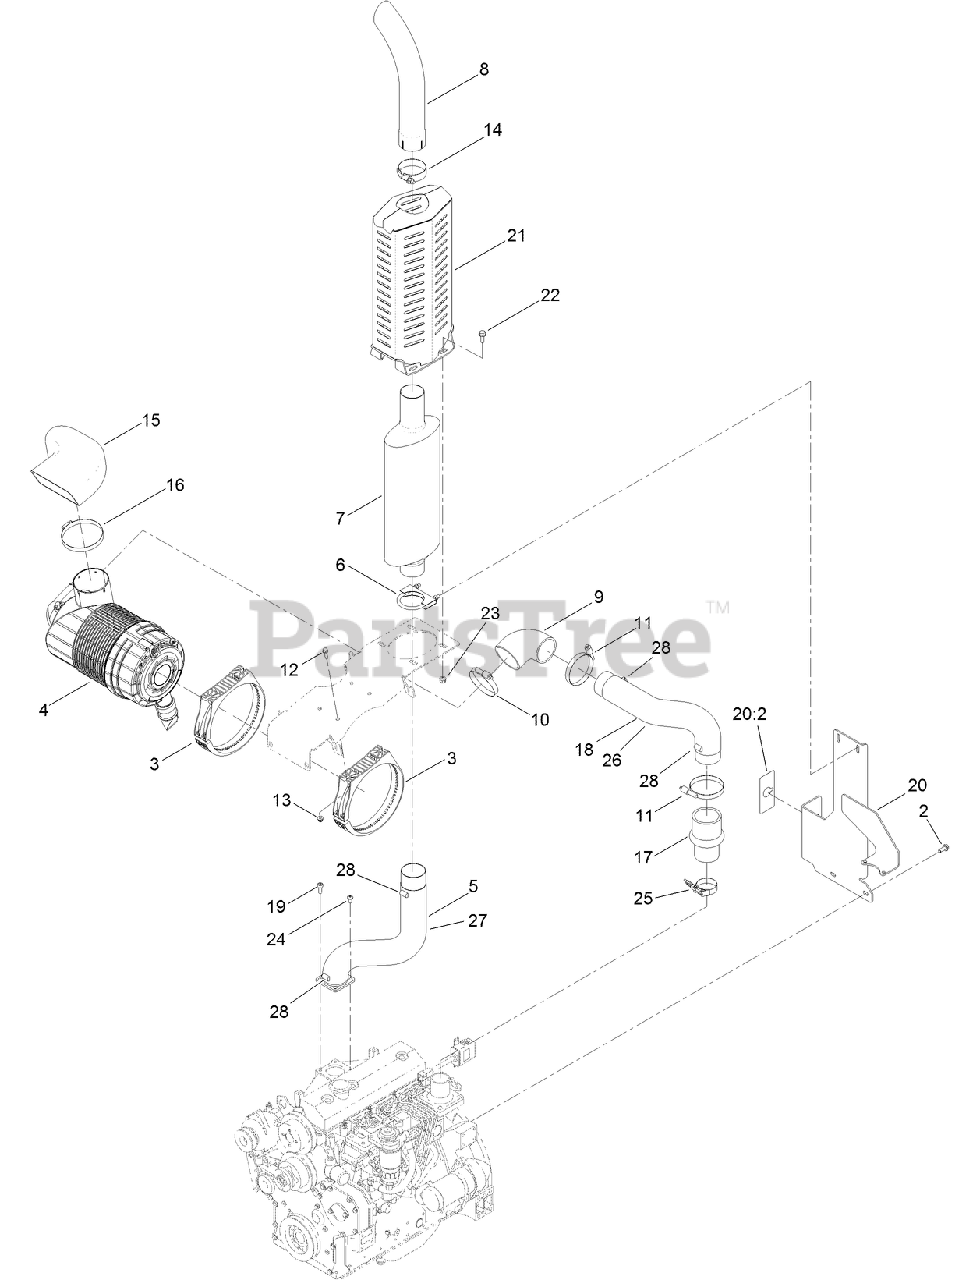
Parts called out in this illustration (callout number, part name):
2	SCREW-HHF
3	BAND-MOUNTING, AIR CLEANER
4	AIR CLEANER ASM
5	TUBE-EXHAUST
6	CLAMP-MUFFLER
7	MUFFLER-VERTICAL, OVAL
8	EXHAUST-STACK
9	CONNECTOR-AIR INTAKE
10	CLAMP-TORQUE, CONSTANT
11	CLAMP-TORQUE, CONSTANT
12	SCREW-HHF
13	NUT-LOCK, HHF
14	CLAMP-MUFFLER
15	INTAKE-Air
16	CLAMP-HOSE, WORM GEAR (HEAVY DUTY)
17	CONNECTOR-INTAKE, AIR
18	TUBE-INTAKE, AIR
19	SCREW-HSH
20	MUFFLER SUPPORT MOUNT ASM
20:2	DECAL-DISCONNECT, BATTERY
21	SHIELD-EXHAUST
22	SCREW-HHF
23	NUT-LOCK, NI
24	SCREW-HSH
25	CLAMP, T-BOLT
26	WRAP-THERMAL, INTAKE
27	WRAP-THERMAL, EXHAUST
28	CLAMP-HOSE
